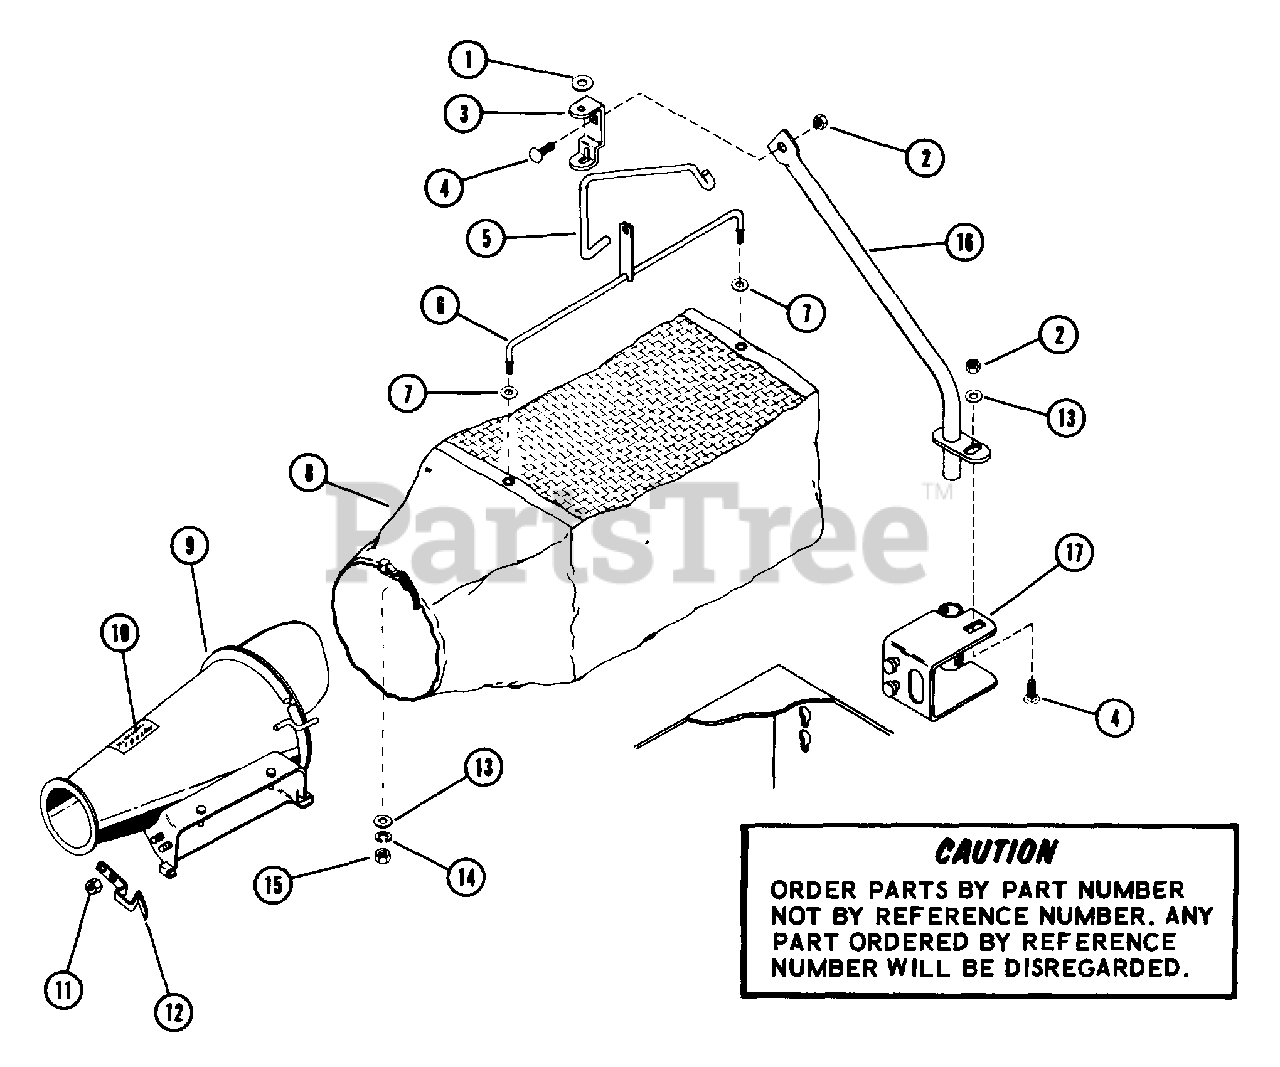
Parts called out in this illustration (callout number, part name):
1	WSHR-FL-STL .323X.625X.062 PL
2	NUT-LK-CTR .375-16 GR A PL
3	STABILIZER BRACKET
4	BLT-RDHDSQNK .38-16X.75 SHT PL
5	STABILIZER ROD
6	CROSS BAR
7	WSHR-FL-STL .38X.875X.083 PL
8	BAG
9	30 IN GRASS CATCHER CONE
10	CAUTION LABEL
11	NUT-LK-FLG .250-20 PL
12	SPRING, FLAT
13	WSHR-FL-STL.406X.812X.065PL
14	WSHR-LK .375X.115 HVY PL
15	NUT-HEX .375-16
16	SUPPORT BAR
17	SUPPORT BAR BRACKET
